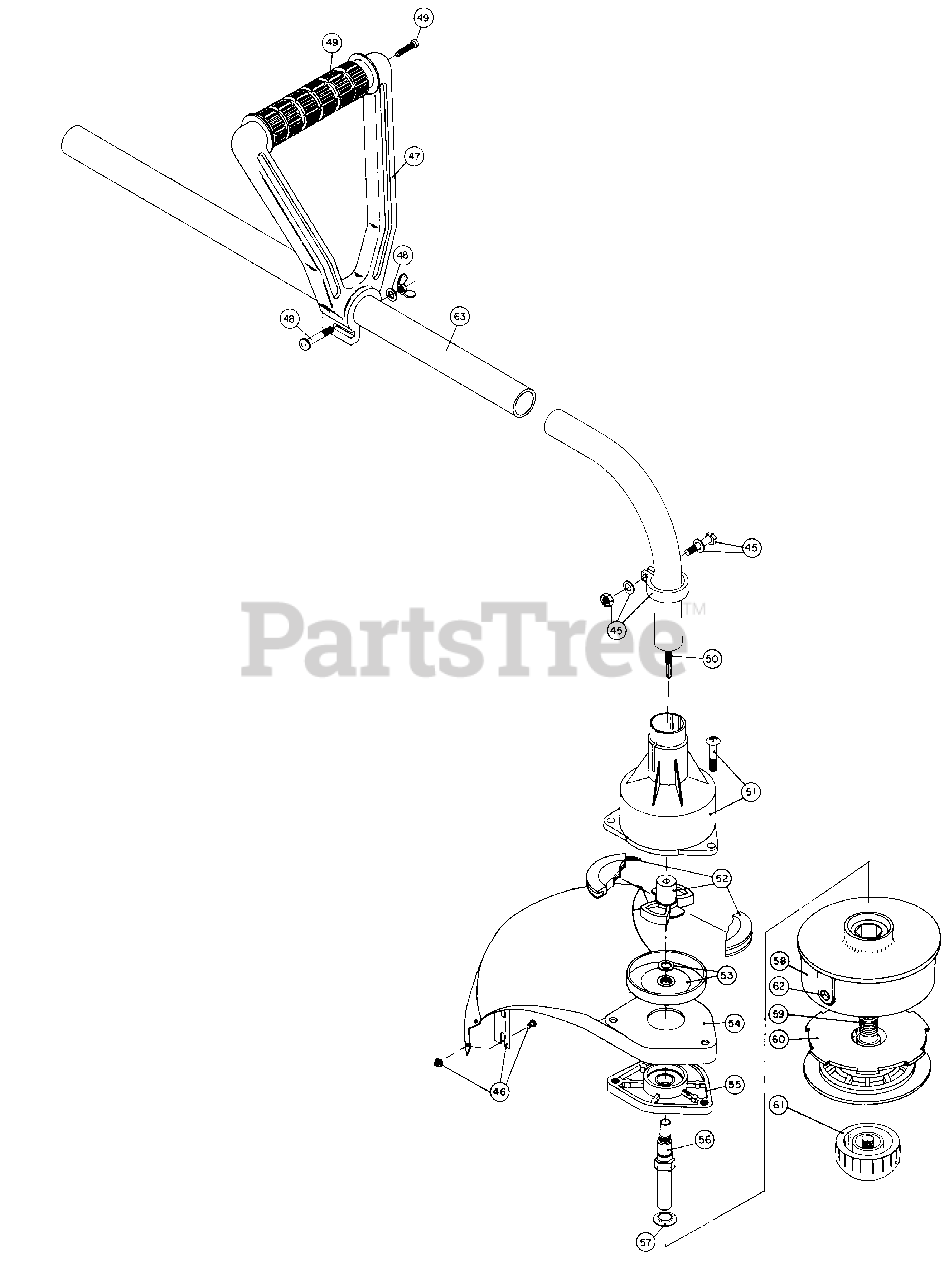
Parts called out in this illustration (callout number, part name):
45	Lower clamp assembly
46	Blade assembly
47	D-handle
48	D-handle hardware
49	Handle grip assembly
50	Flexible drive shaft
51	Clutch housing assembly
52	Clutch rotor assembly
53	Clutch drum assembly
54	Lower guard
55	Lower bearing housing
56	Lower drive shaft assembly
57	Spool retainer (10 pack)
58	Outer spool
60	Inner reel
61	Bump head knob assembly
63	Drive shaft housing assembly
